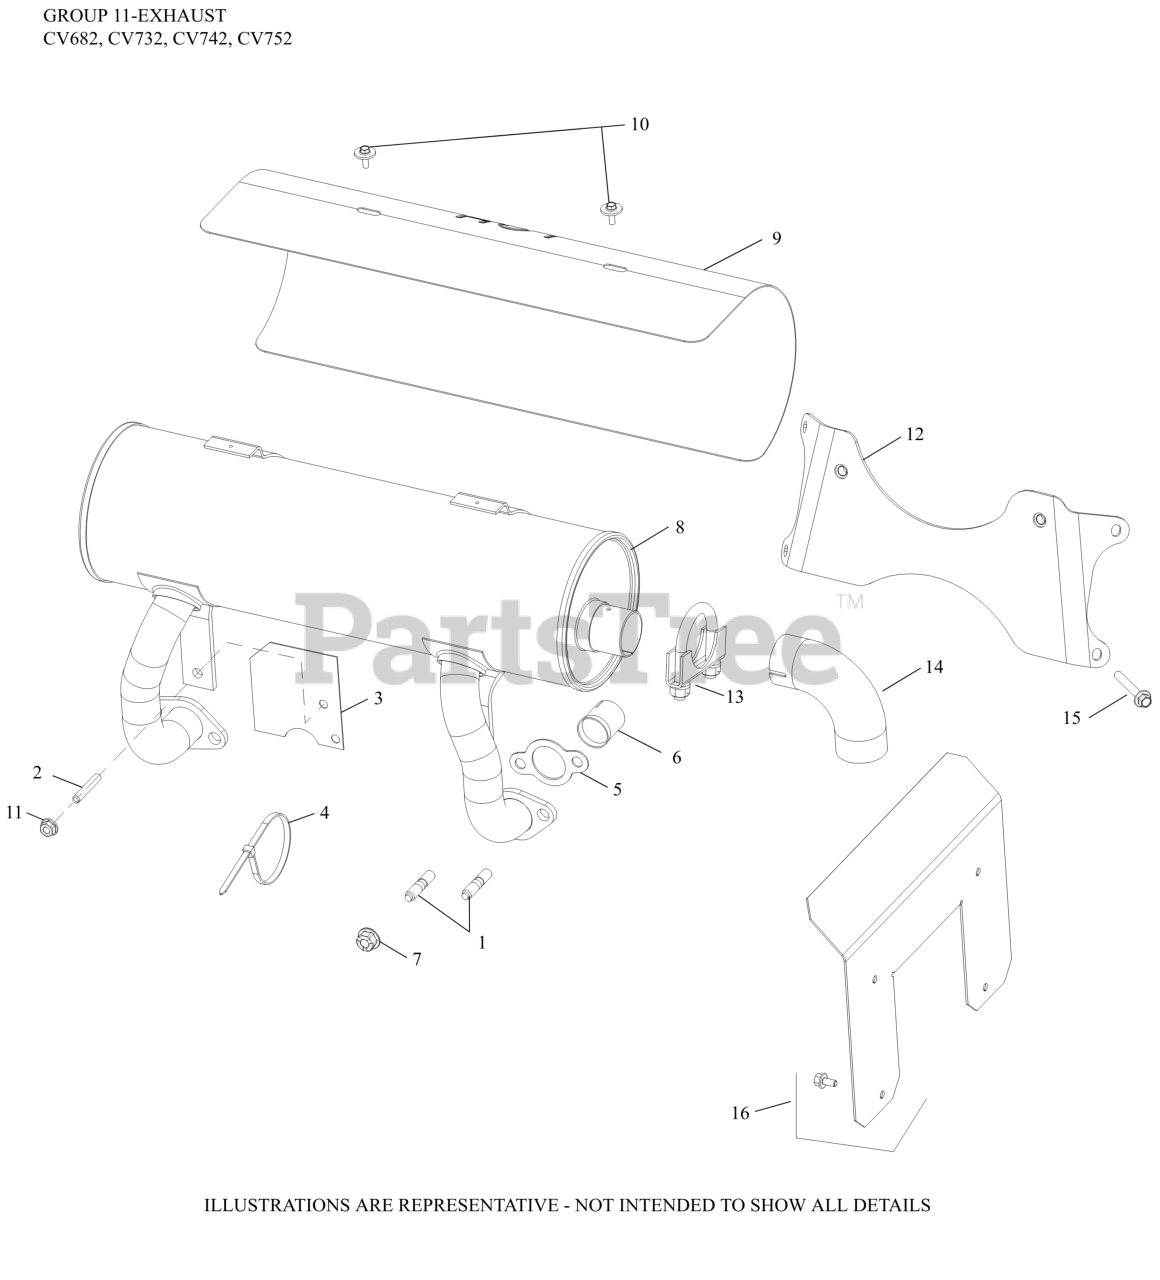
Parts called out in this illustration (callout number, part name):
5	GASKET, EXHAUST
6	LINER, EXHAUST PORT
7	NUT, HEX FLANGE LOCK (M8)
